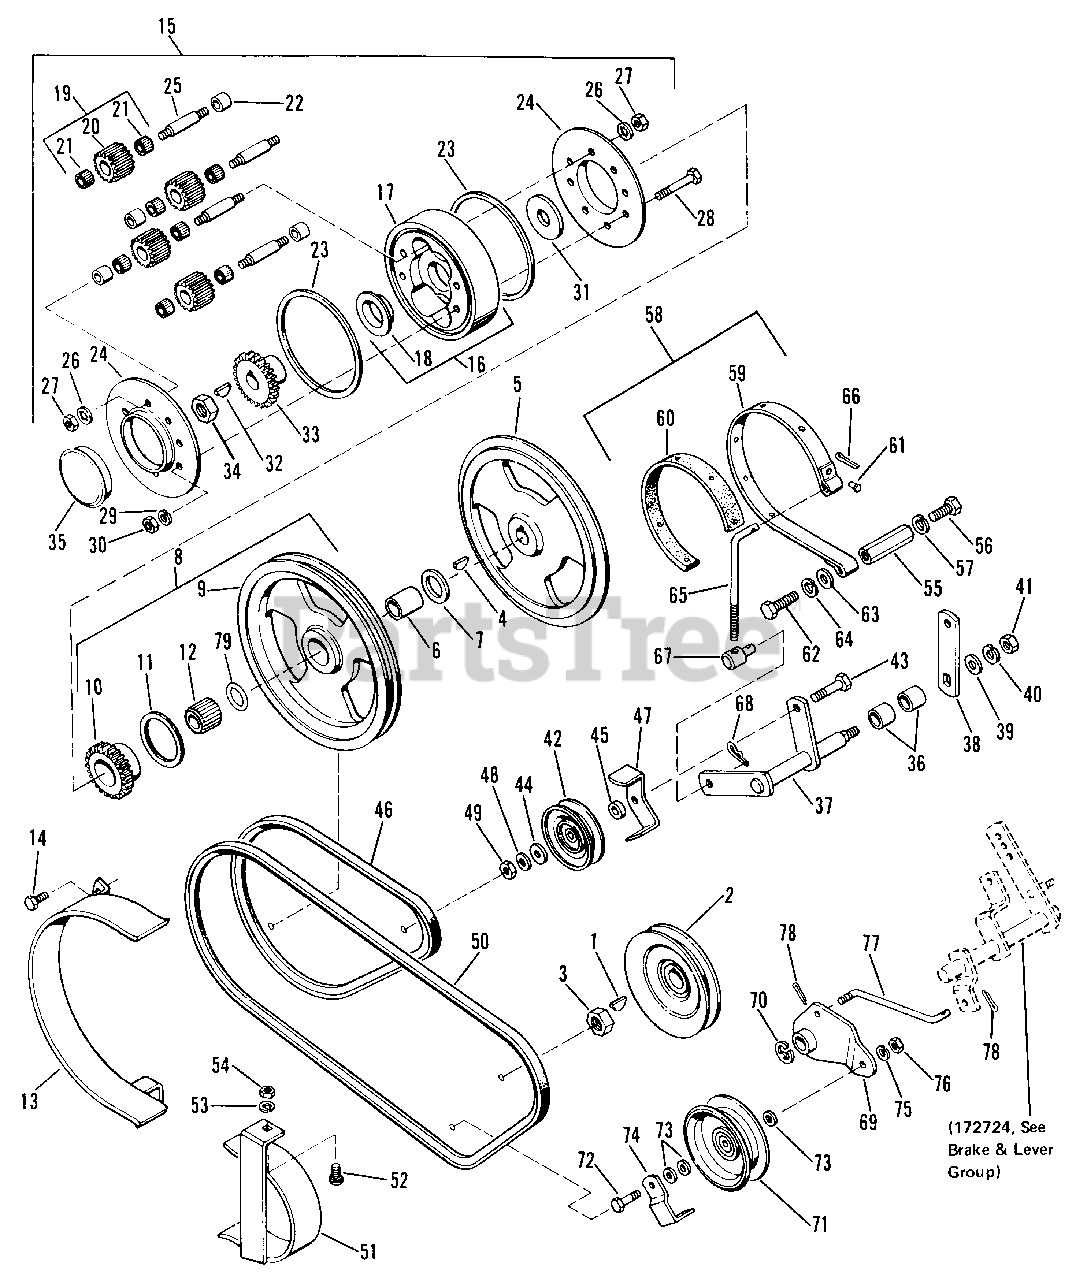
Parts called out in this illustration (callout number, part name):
1	Hi Pro Key, 3/16" x 3/4"
3	Hex Jam Nut, 3/4"-16
4	Key, Woodruff No. 9
5	Half Sheave
7	Thrust Bearing
8	Sheave Assembly
10	Gear Differential
12	Bearing, Roller
13	Pulley Guard Assembly
14	Taptite Hex Hd. Washer Screw, 5/16"-18 x 5/8"
15	Planetary Assembly
16	Planetary Carrier Sub-Assy.
17	Planetary Carrier
18	Bearing, Flange
19	Pinion Differential Assembly
20	Pinion Differential
21	Bearing, Needle
22	Bearing, Sleeve
24	Differential, Cover
25	Pinion, Pin
26	Lockwasher, Shakeproof
27	Full Hex Nut, 5/16"-18
28	Hex Capscrew, 5/16"-18 x 2"
29	Lockwasher, 5/16"
30	Full Hex Nut, 5/16"-18
31	Washer, Thrust
32	Key, Woodruff, 3/16" x 3/4"
33	Gear, Differential
34	Hex Jam Nut, 3/4"-16
37	Lever Assembly
39	Plain Washer, 3/8"
40	Lockwasher, 3/8"
41	Full Hex Nut, 3/8"-16
42	Idler Pulley
43	Hex Capscrew, 3/8"-16 x 1-1/2"
44	Plain Washer, 5/16"
47	Guide Belt
48	Lockwasher, 3/8"
49	Full Hex Nut, 3/8"-16
51	Belt Guard Assembly
52	Carriage Bolt,3/8"-16 x 3/4"
53	Lockwasher, 3/8"
54	Full Hex Nut, 3/8"-16
55	Brake Anchor
56	Hex Capscrew, 3/8"-16 x 1"
57	Lockwasher, 3/8"
58	Brake Band Assembly
60	Brake Lining
61	Rivet No. 7 x 1/4"
62	Hex Capscrew, 3/8"-16 x 1-1/2"
63	Plain Washer, 5/16"
64	Lockwasher, 3/8"
66	Cotter Pin, 3/32" x 3/4"
68	Cotter Pin, 3/32" x 3/4"
69	Idler Lever Assembly
70	"E" Ring
71	Pulley
72	Hex Capscrew, 3/8"-16 x 1-1/2"
73	Plain Washer, 5/16"
74	Guide Belt
75	Lockwasher, 3/8"
76	Full Hex Nut, 3/8"-16
77	Clutch Link
78	Cotter Pin, 3/32" x 3/4"
